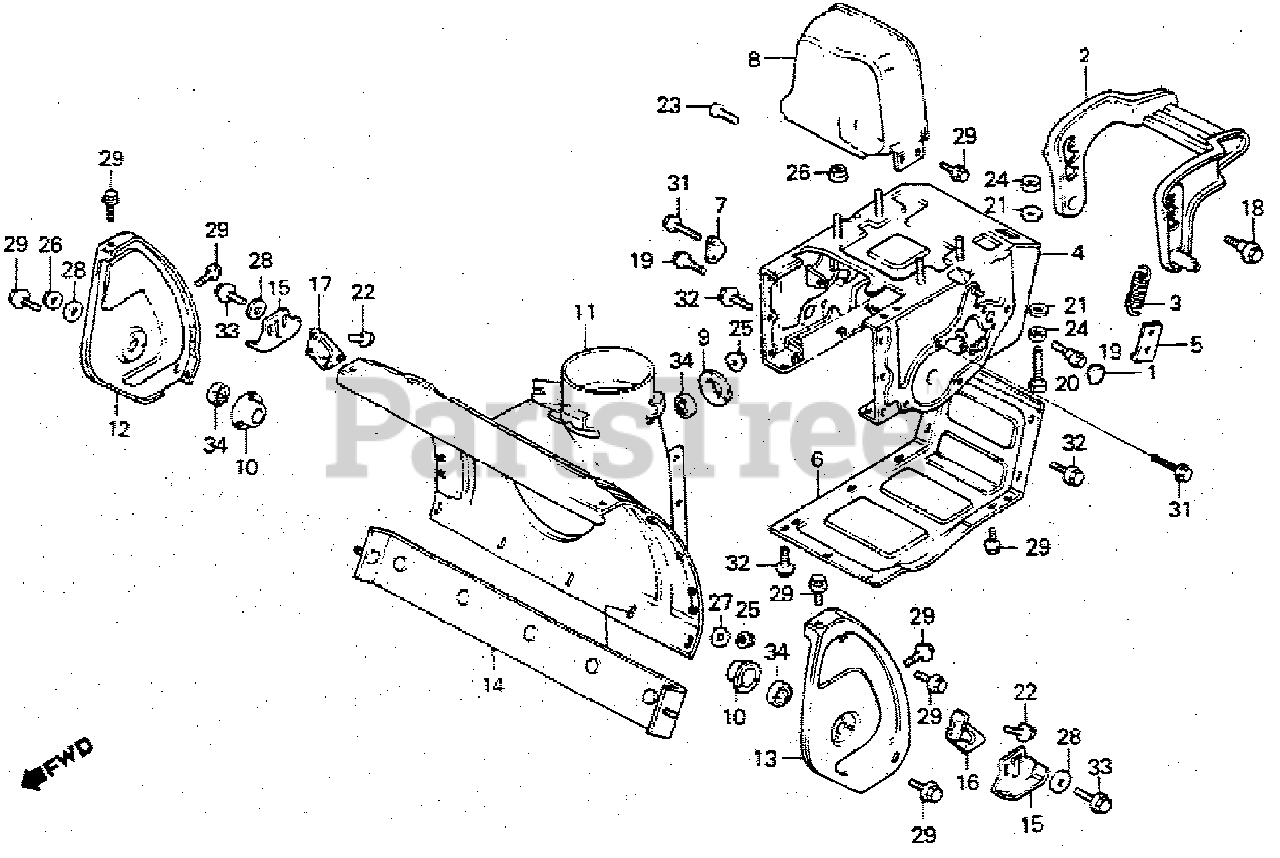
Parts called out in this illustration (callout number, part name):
1	GROMMET, GUIDE ROLLER
2	PLATE, HEIGHT ADJUSTING (NOT AVAILABLE)
4	BED, ENGINE
6	COVER (LOWER) (NOT AVAILABLE)
7	PLATE, DISK HOLDER SHAFT
8	COVER, BELT
9	HOLDER, L. AUGER
10	HOLDER, AUGER BEARING
11	HOUSING, AUGER
12	COVER, R. AUGER SIDE (NOT AVAILABLE)
12	COVER, R. AUGER SIDE (14")
13	COVER, L. AUGER SIDE (NOT AVAILABLE)
13	COVER, L. AUGER SIDE (14")
14	GUARD, AUGER HOUSING
15	SKID, AUGER
19	BOLT, TRANSMISSION SETTING
20	BOLT, ADJUSTING
21	WASHER (8MM)
23	SCREW, PAN (6X18)
24	NUT, HEX. (8MM)
25	NUT, FLANGE (6MM)
26	NUT, FLANGE (8MM)
27	WASHER, PLAIN (6MM)
28	WASHER, PLAIN (8MM)
29	BOLT, FLANGE (6X10)
30	BOLT, FLANGE (6X12)
30	BOLT, FLANGE (6X10)
31	BOLT, FLANGE (6X18)
32	BOLT, FLANGE (8X14)
33	BOLT, FLANGE (8X16)
33	BOLT, FLANGE (8X14)
34	BEARING, RADIAL BALL (6203UU)
